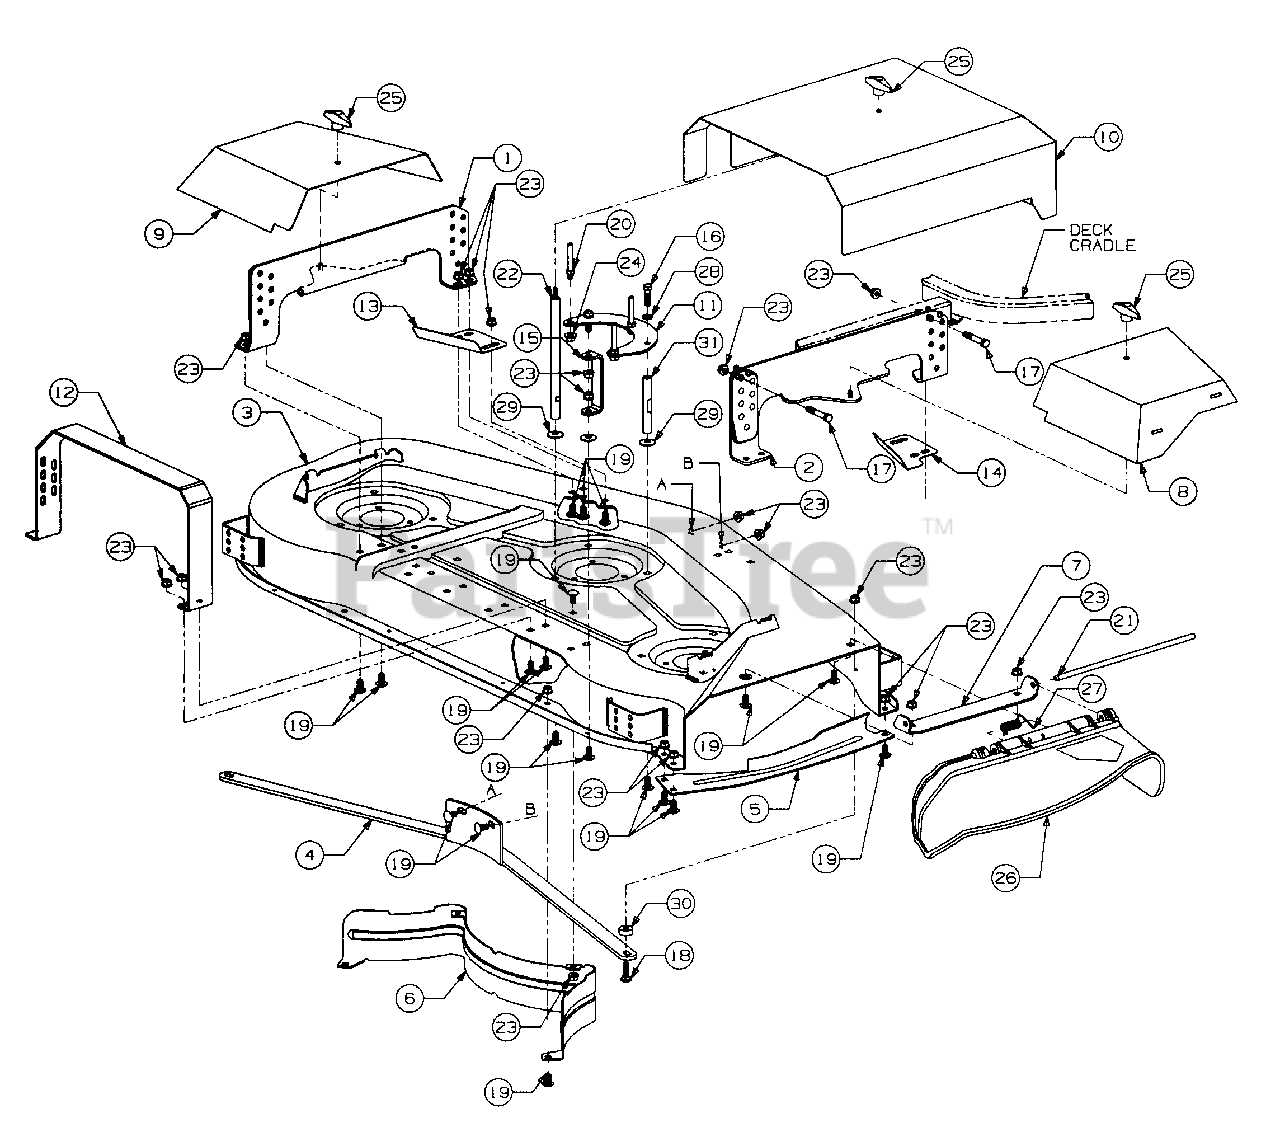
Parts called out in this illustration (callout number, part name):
3	Housing Assy w/Graphics 54' Mower
11	Plate, Belt Guide Mtg
12	Bracket, Belt Cover Support
13	Plate, LH Filler
14	Plate, RH Filler
15	Support, Belt Guide
16	Screw, Hex Cap, 3/8-16 x 1.25 Lg GR5
17	Screw, Hex Cap, 3/8-16 x 2.25 Lg GR5
18	Bolt, Carriage, 3/8-16 x 1.25 Lg GR5
19	Bolt, Sht Nk Carriage, 3/8-16 x.75 Lg GR5
20	Stud, 3/8-16 x 2.68 Lg
21	Pin, Hinge, .375 x 12.55 Lg
22	Post, Belt Cover Support
23	Nut, Hex Flanged Lock, 3/8-16
24	Nut, Hex Flange Lock, 3/8-16
25	Knob, Wing Nut
26	Deflector, Chute
27	Spring, Torsion
28	Washer, Lock, 3/8
29	Washer, Bell, 3/8 x 1. 1 25 x .062 Thk ..
30	Spacer, Front Bar
31	Post, Belt Guide Mtg
